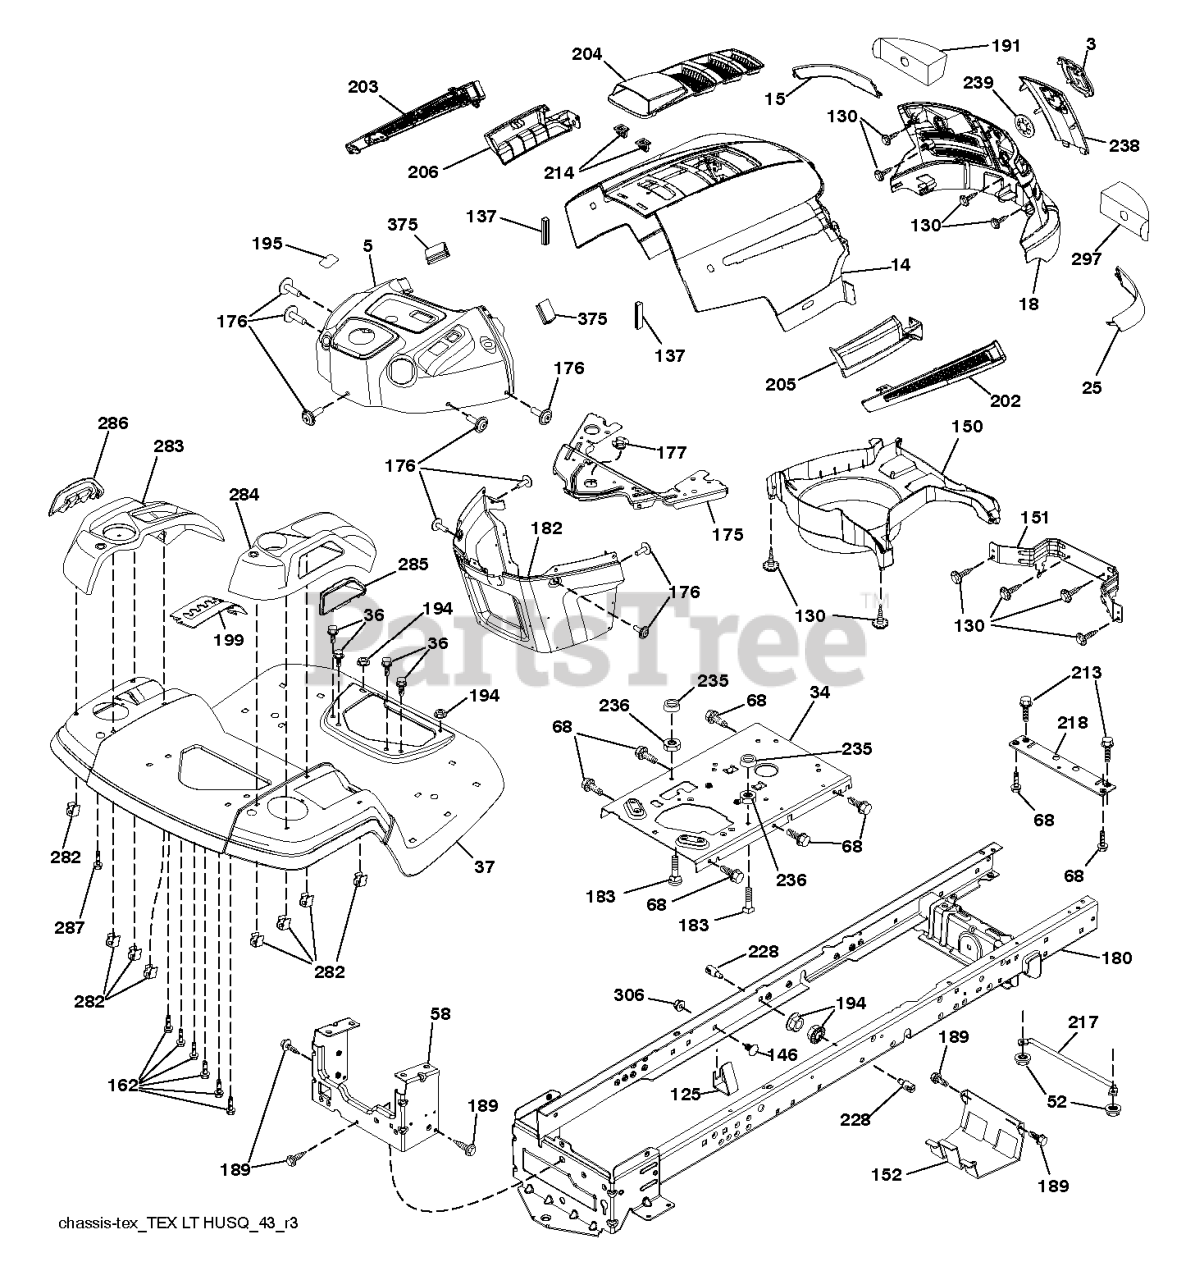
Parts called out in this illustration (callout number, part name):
3	LOGO.HUSQ.GT.LT.CROWN.H
5	DASH.UPPER.HUSQ.LT.MAN.NO-CHK
14	HOOD.HUSQVARNA.LT.ORANGE
15	LENS.HUSQVARNA LT.RH
18	GRILLE.SVC.HUSQVARNA.GREY
25	LENS.HUSQVARNA LT.RH
34	PLATE.ENGINE.WELDED.CHASSIS
36	SCREW 5/16"
37	FENDER.TLT.FS.W/CUPHLD.ORANGE
52	LOCKNUT
58	DRAWBAR UPPER 2PC SMALL FENDER
68	Screw 5/16-18 x 1/2 Hex, Self Tapping 5/16-18 x 1/2
125	CLIP.FUEL.LINE
130	SCREW.#10 X 0.750.BOS
137	BUMPER DASH
146	BOLT.RDHD.SHT.SQNK.3/8-16X5/8
151	BRACKET PIVOT
152	SHIELD.BROWNING.W/TEX
162	SCREW.HI-LO.CONSOLE
175	CROSSMEMBER
176	SCREW.#10-24X5/8.RN.QU
177	BUSHING STEERING
180	CHASS.WLDMNT.TL.12GA/2P.48/54
182	DASH.LOWER.PREDATOR LT
183	BOLT.5/16-18X1-1/4 FULL THD
189	SCREW
191	INSERT.REFLECTIVE.RH.
194	NUT LOCK HEX FLANGE 5/16-18
195	PLUG DASH
199	PLATE.DECK.LIFT.HUSQ.LT
202	VENT.SIDE.HUSQVARNA.LT.RT
203	VENT.SIDE.HUSQVARNA.LT.LFT
204	SUBASM.TOP.VENT.HUSQ.LT
205	SKIRT.SIDE.HUSQVARNA.LT.RT
206	SKIRT.SIDE.HUSQVARNA.LT.LEFT
213	BOLT
214	CLIP.RETAINER.TINNER.
217	ROD.PIVOT.HOOD
218	X-PIECE.HOOD.STOP.NON/
228	STUD.FASTNER.W/ANTI-ROTATE
235	SPACER FENDER
236	NUT.CENTERLOCK.5/16-
238	TRIM.HUSQ LT.668
282	CLIP.RETAINER.CONSOLE.LT.HUSQ
283	CONSOLE.ASM.LFT.RSF.HUSQ.LT
284	CONSOLE CONSOLE.HUSQ.SHIFT.HYD
285	CONSOLE INSERT RH
286	CONSOLE.INSRT.LH.HUSQ.LT.BLACK
287	SCREW 1/4X20
297	INSERT REFLECTIVE
306	NUT LOCK FLG 3/8-16 UNC
375	BUMPER CLIP-ON. DASH 1"
